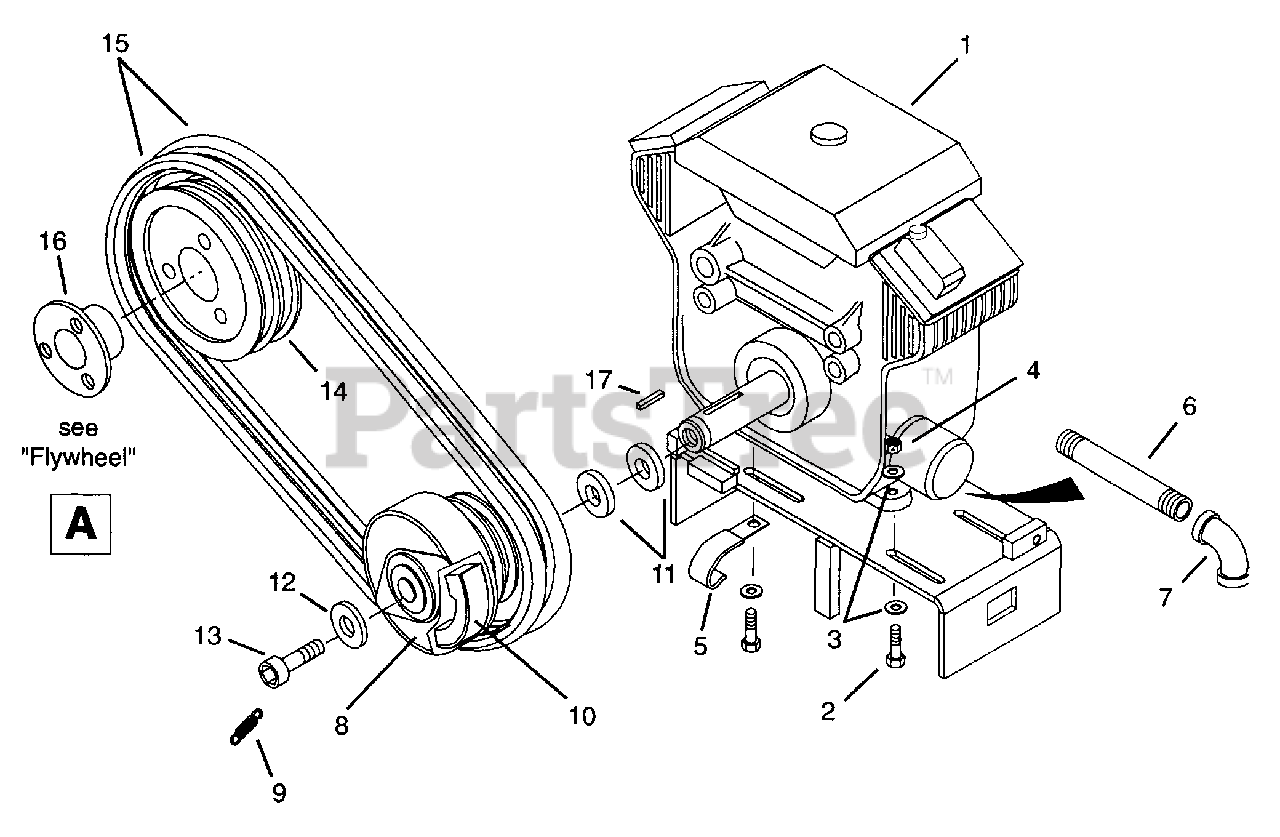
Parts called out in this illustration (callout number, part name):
1	25 HP Kohler Command PS-68548
2	Bolt-Hex .38-16 x 1.75 Grade 5
3	Washer-Flat-Steel .438 x 1.00 x .083
4	Nut-Locking-Center .38-16
5	Clamp-Line
6	Nipple .38 x 7.5
7	Elbow .375-18
8	Clutch 1.125 Bore
8	Clutch
9	Spring-Clutch
10	Shoe-Clutch
11	Shim 25 HP
11	Spacer
11	Bushing-Narrow Rim 14 GA 1-1/2 x 2-1/4
12	Washer 25 HP
12	Washer-Flat .640 x 1.81 x 2.50
13	Screw- Socket Head .43-20 x 1.50
13	Bolt-Socket Head SPL .62-18 x 1.75
15	V-Belt 23 HP Matched Set
16	Bushing SK x 1-1/2
17	Key-Square .25 x 2.50 x .25
17	Key-Straight .38 x 2.75 x .38
